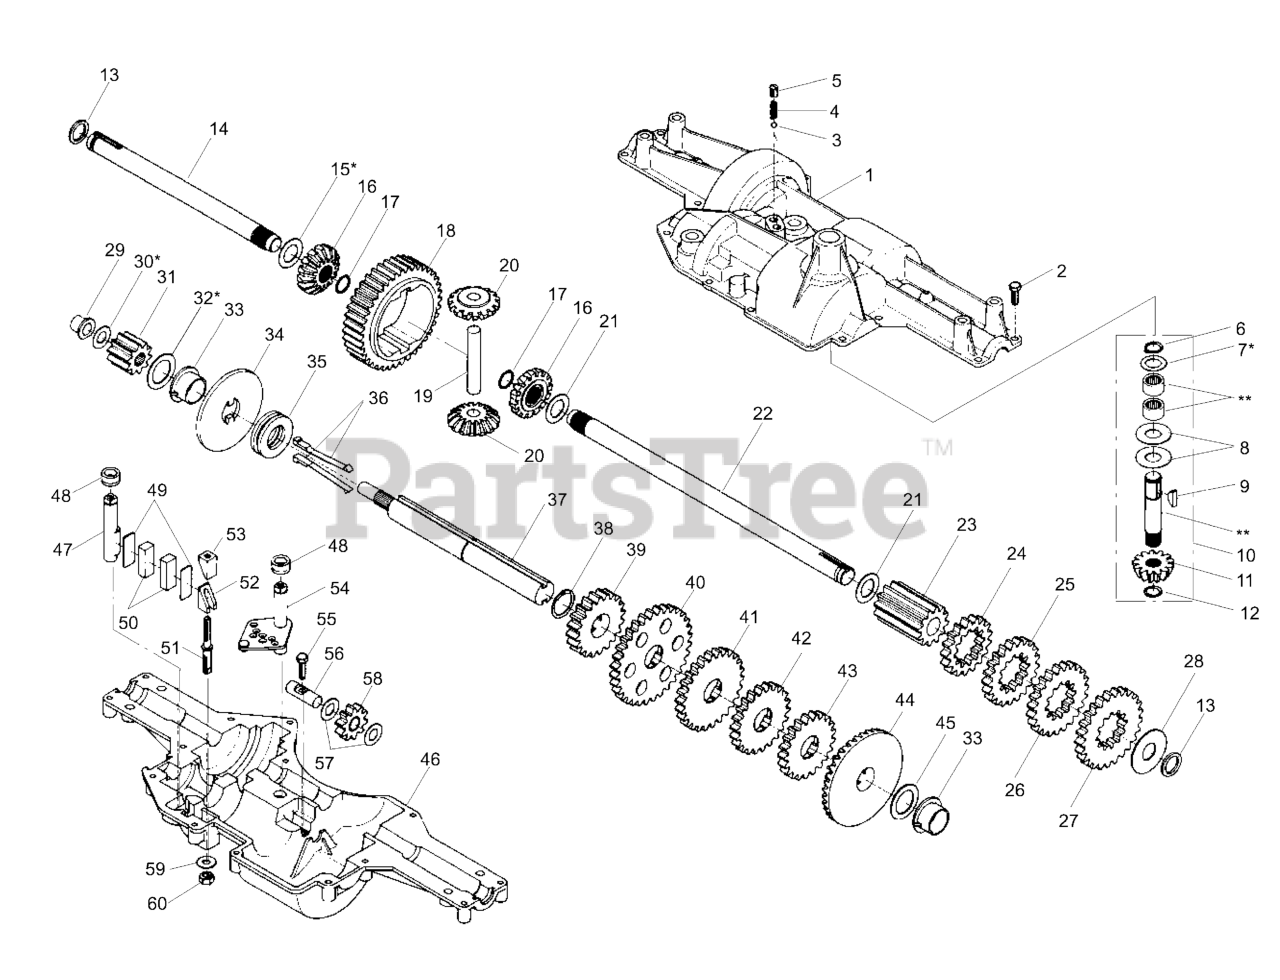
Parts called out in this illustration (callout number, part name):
1	Housing, Upper
2	Screw, Tapping 1/4-20x .734
3	Ball, Detent
4	Spring, Detent (2 req.)
5	Screw, Set
6	Ring, Retainer
7	Washer, Plain .632 x 1.00 x .031
7	Washer, Plain .632 x 1.00 x .036
7	Washer, Plain .632 x 1.00 x .041
7	Washer, Plain .632 x 1.00 x .046
7	Washer, Plain .632 x 1.00 x .050
7	Washer, Plain .632 x 1.00 x .060
7	Washer, Plain .632 x 1.00 x .082
8	Washer, Plain .632 x 1.38 x .046 (2 req.)
9	Key, Woodruff, #9
10	Assembly Kit, Input Shaft
11	Pinion, Bevel 13T
12	Ring, Retainer
13	Seal, Felt
14	Axle, L.H.
15	Washer, Plain .758 x 1.25 x .020
15	Washer, Plain .758 x 1.25 x .025
15	Washer, Plain .758 x 1.25 x .031
15	Washer, Plain .758 x 1.25 x .035
15	Washer, Plain .758 x 1.25 x .040
15	Washer, Plain .758 x 1.25 x .045
15	Washer, Plain .758 x 1.25 x .050
16	Gear, Miter - 15T
17	Ring, Retainer (2 req.)
18	Gear, Spur -39T
19	Shaft, Cross
20	Gear, Miter - 15T
21	Washer, Plain .758 x 1.25 x .062 (2 req.)
22	Axle, R.H.
23	Gear, Spur -12T
24	Gear, Spur -17T
25	Gear, Spur -21T
26	Gear, Spur -23T
27	Gear, Spur -25T
28	Washer, Plain .758 x 1.88 x .062
29	Bearing, Flange
30	Washer, Plain .505 x .942 x .010
30	Washer, Plain .505 x .942 x .015
30	Washer, Plain .505 x .942 x .020
30	Washer, Plain .505 x .942 x .026
30	Washer, Plain .505 x .942 x .030
30	Washer, Plain .505 x .942 x .040
30	Washer, Plain .505 x .942 x .060
31	Gear, Spur -10T
32	Washer, Plain 1.01 x 1.50 x .061
32	Washer, Plain 1.01 x 1.50 x .075
32	Washer, Plain 1.01 x 1.50 x .090
33	Bearing, Flange (2 req.)
34	Disc, Brake
35	Collar, Clutch
36	Key, Clutch
37	Shaft, Drive
38	Ring, Retainer
39	Gear, Spur -20T
40	Gear, Spur -32T
41	Gear, Spur -26T
42	Gear, Spur -22T
43	Gear, Spur -21T
44	Gear, Bevel, Comb. 39 & 18T
45	Washer, Plain 1.01 x 1.50 x .061
46	Housing, Lower
47	Shaft, Brake
48	V-Ring (2 req.)
49	Spacer (2 req.)
50	Puck, Friction (2 req.)
51	Stud, Adjustment -Brake
52	Cam, Adjustment -Slotted
53	Cam, Adjustment -Brake
54	Assembly, Shifter
55	Screw, Tap 1/4 -18 x .875
56	Shaft, Idler
57	Washer, Plain .505 x .942 x .015
58	Assembly, Gear Spur -10T
59	Washer, Plain .325 x .750 x .059
60	Locknut 5/16 -24
61	Grease
